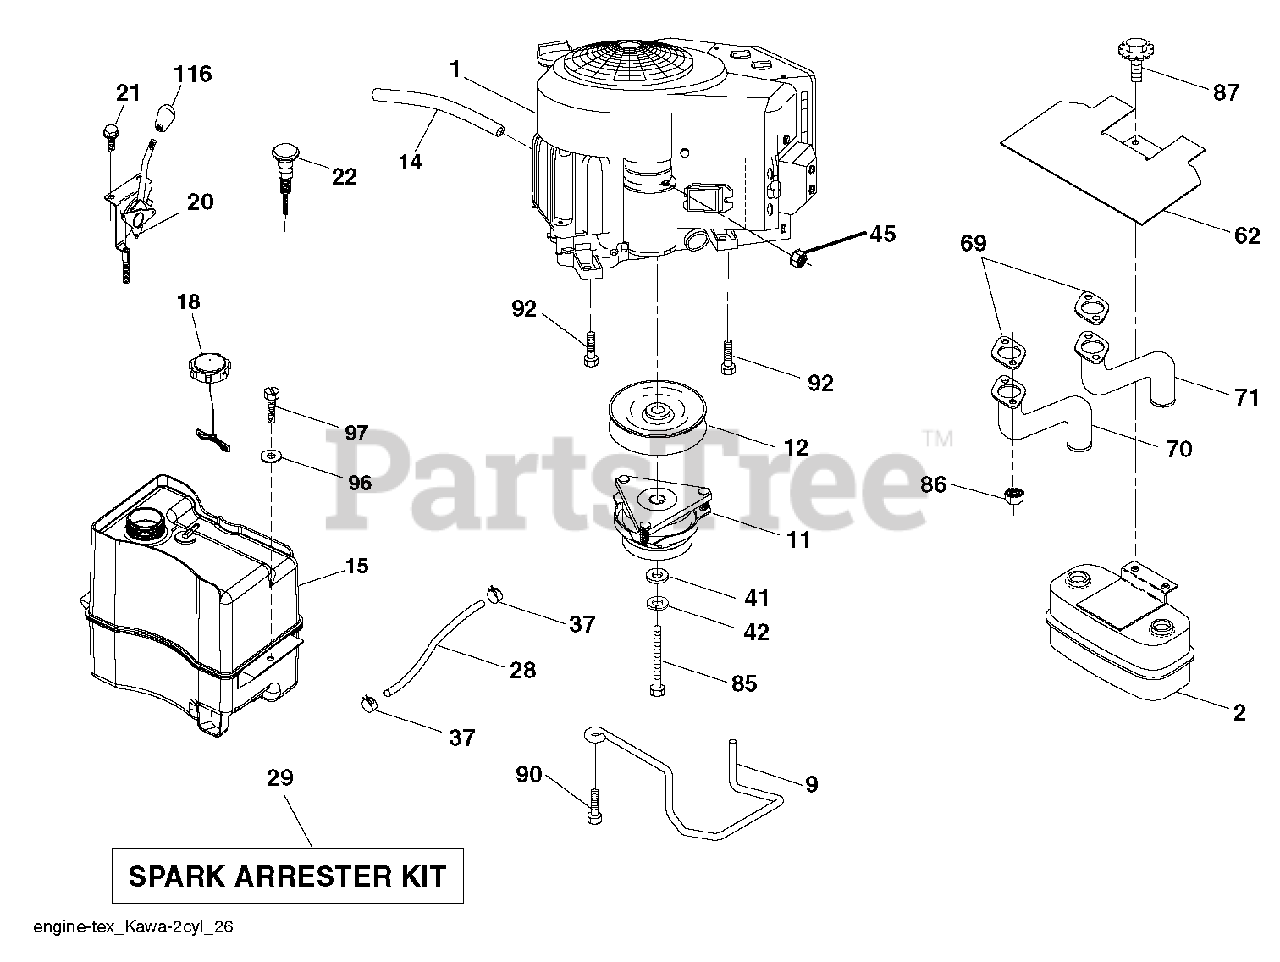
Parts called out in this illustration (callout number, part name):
2	MUFFLER.ASM.TWN.EXTNDED.DFLCTR
9	KEEPER BELT ENGINE
11	CLUTCH.ELECTRIC.LT.48"*
12	PULLEY.ENGINE.TUFFTORQ
14	TUBE, DRAIN OIL ASM.
15	TANK.ASSEMBL.2.5GAL.NON-EPA
18	CAP ASM.FUEL.2.25"FR.
20	CONTROL.THROTTLE.PRO.
21	SCREW.#10 X 0.750.BOS
22	CONTROL.CHOKE.ERGO.PUSH-IN.BLA
28	LINE.FUEL.64"REAR.EMIS
29	KIT.SPARK ARRESTOR 794945 B&S
37	HOSE CLAMP
42	LOCKWASHER
45	NUT
62	SHIELD.HEAT.MUFFLER
70	TUBE.EXHAUST.LH.FR961/FR730
71	TUBE.EXHAUST.RH.FR961/FR730
85	BOLT HEX 7/16-20X4-1/4"
86	NUT.HEX.FLANGE.TOPLOCK
87	Bolt, 5/16-18 X 1-3/4
90	SCREW 3/8-16X1
92	SCREW 3/8-16X1
